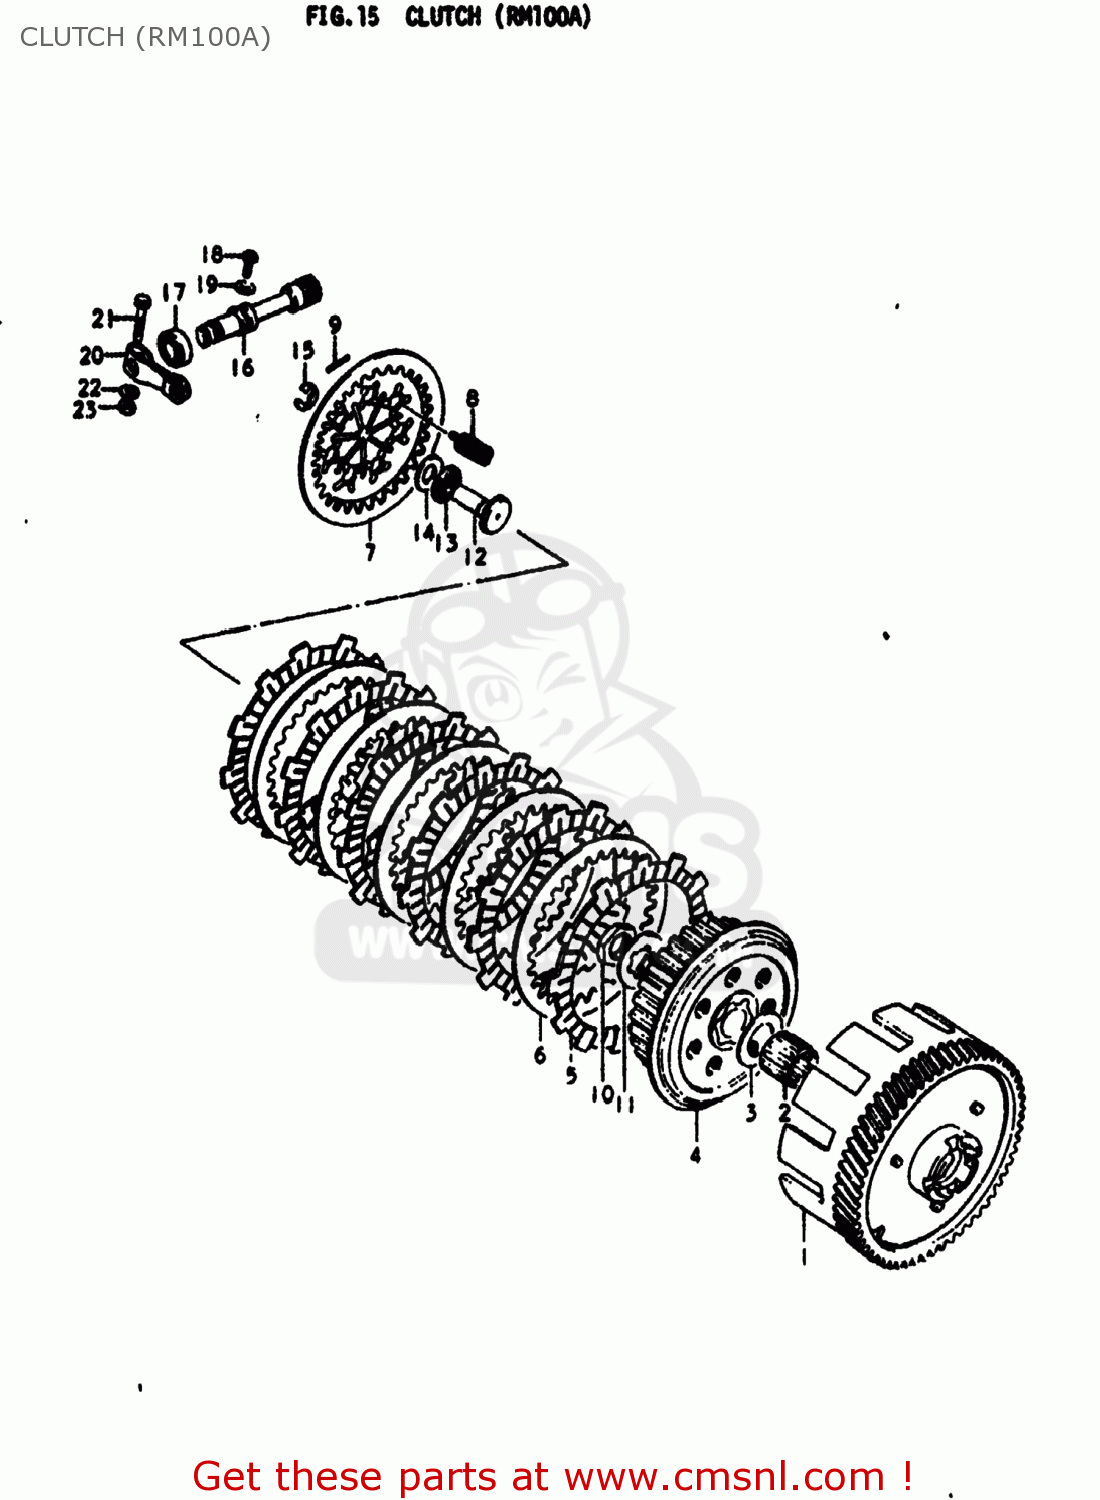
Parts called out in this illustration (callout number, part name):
1	GEAR ASSEMBLY,PRIMARY DRIVE
2	BEARING
3	WASHER
4	HUB,CLUTCH SLEEVE
5	PLATE,CLUTCH DRIVE
6	PLATE,CLUTCH DRIVEN (NAS)
7	PLATE,CLUTCH PRESSURE
8	SPRING
9	PIN(2.5X19.8)
10	NUT
11	WASHER,LOCK
12	RACK,CLUTCH RELEASE
13	BEARING(10X22X2.8)
14	WASHER
15	E RING 8MM
16	PINION,CLUTCH RELEASE
17	OIL SEAL
18	BOLT(6X12)
19	WASHER
20	ARM,CLUTCH RELEASE
21	BOLT
22	WASHER
23	NUT
